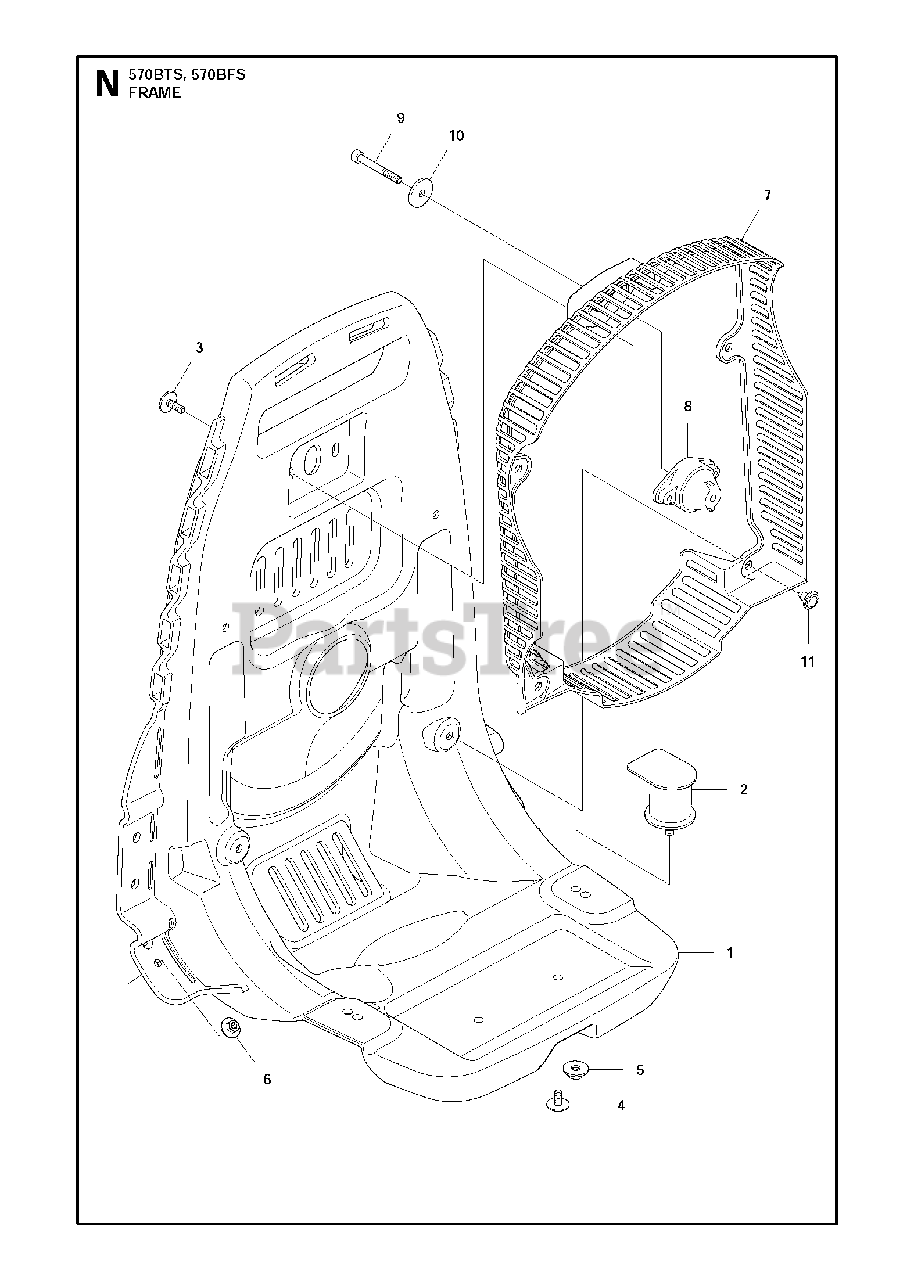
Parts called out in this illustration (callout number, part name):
7	NET
8	DAMPER UPPER
9	BOLT
